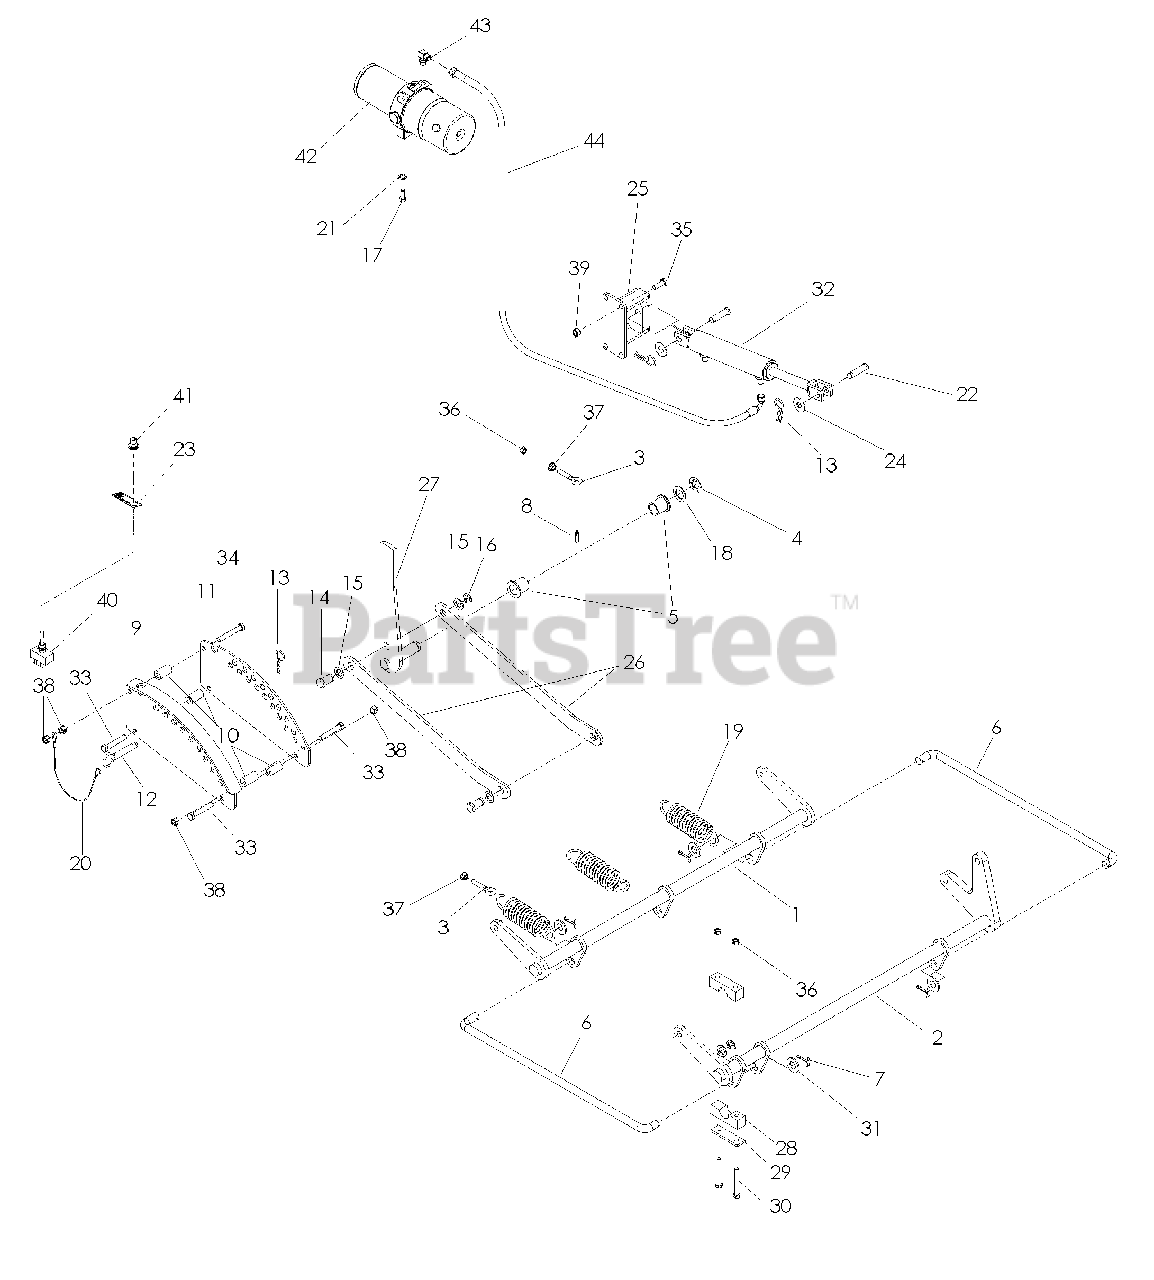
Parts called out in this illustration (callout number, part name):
1	LIFT SHAFT ASSEM, REAR
2	LIFT SHAFT, FRONT
4	E-RING .875
5	BUSHING, FLANGED
6	CONNECTING LINK
7	ZERK, LONG
8	COTTER PIN 5/32 x 1 1/4
9	ADJUSTMENT PLATE
11	ADJUSTMENT PLATE
14	CLEVIS PIN
15	BUSHING .625 MACHINE
16	E-RING .625
17	HCS 3/8-18 x 3/4
18	BUSHING .875 MACHINE
19	SPRING, EXTENSION
21	WASHER 3/8 SPLIT LOCK
22	CLEVIS PIN, 1/2x 1 3/4
23	DECAL, LIFT SWITCH
24	WASHER 1/2 FLAT
25	CYLINDER MOUNT
26	LIFT LINKAGE
27	LIFT LEVER
28	PILLOW BLOCK
29	REINFORCEMENT BAR
30	HCS 5/16-18 x2 1/2
31	WASHER 5/8 SAE FLAT
33	HCS 3/8-16 x2 1/4
34	HCS 3/8-18 x2 1/2
35	HCS 3/8-16 x 1
36	NUT 5/16-18 HEX CTRLK
37	NUT 5/16-18 WHIZ
38	NUT 3/8-16 HEX CTRLK
39	NUT 3/8-16 HEX NYLOC
41	BOOT, SWITCH
42	POWER UNIT
